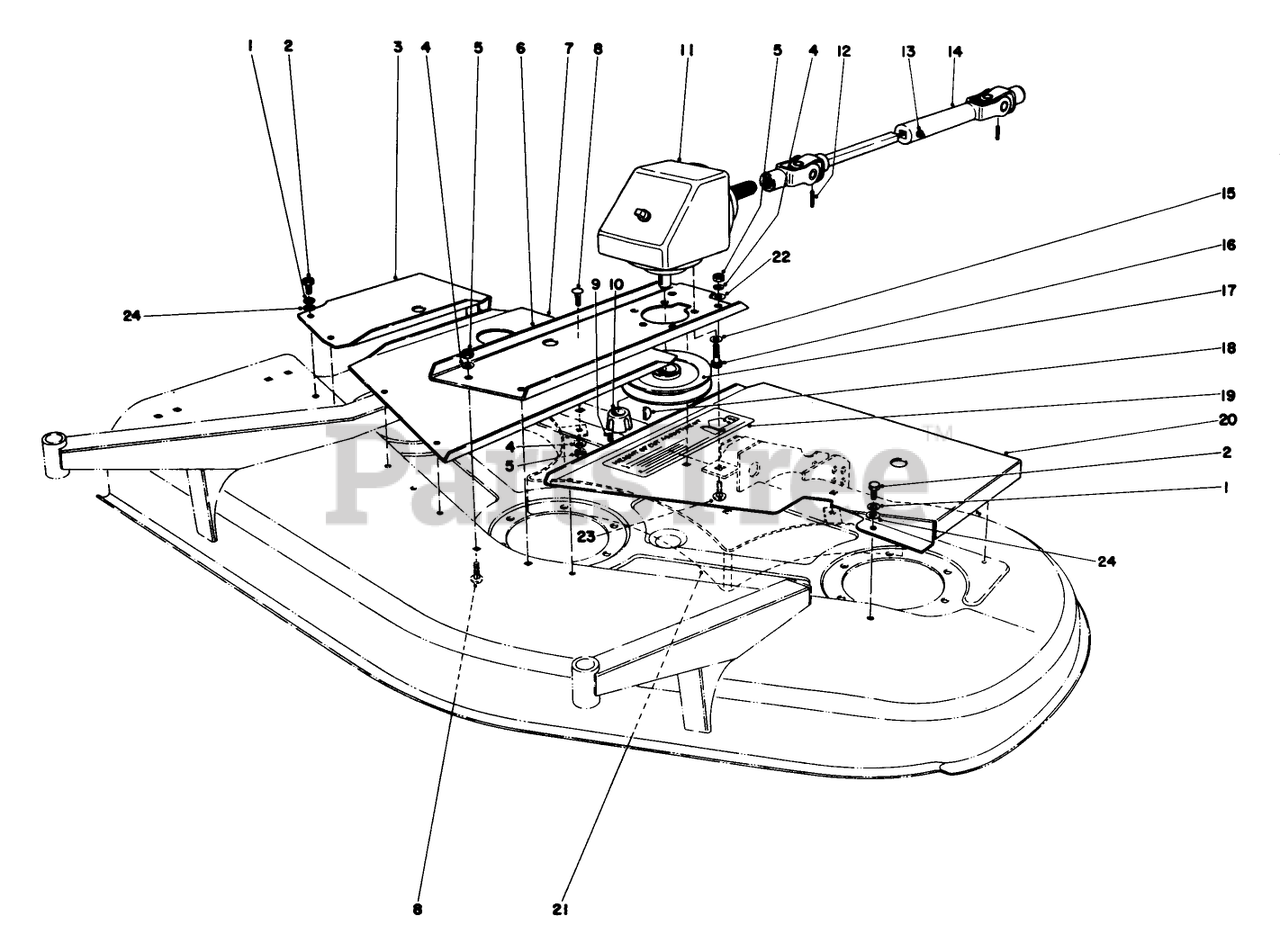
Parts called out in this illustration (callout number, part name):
1	WASHER-LOCK
2	SCREW THD 1/4 20 5/8
3	Deck Cover Right
4	WASHER-LOCK
5	NUT-HEX
6	Gear Box Base
7	CTR DECK COVER WA R
8	SCREW-CARR
9	SCREW-SET, HSH
10	BUSHING-LOCK, TAPER
11	GEAR BOX ASM
12	PIN-ROLL
13	FITTING-GREASE
14	UNIVERSAL JOINT
15	WASHER-LOCK
16	SCREW-HSH
17	PULLEY WA BO
18	KEY-WOODRUFF
19	H O C DECAL
20	Deck Cover Left
21	BAFFLE WA B
22	WASHER-FLAT
23	SCREW-CARR
24	WASHER-FLAT
